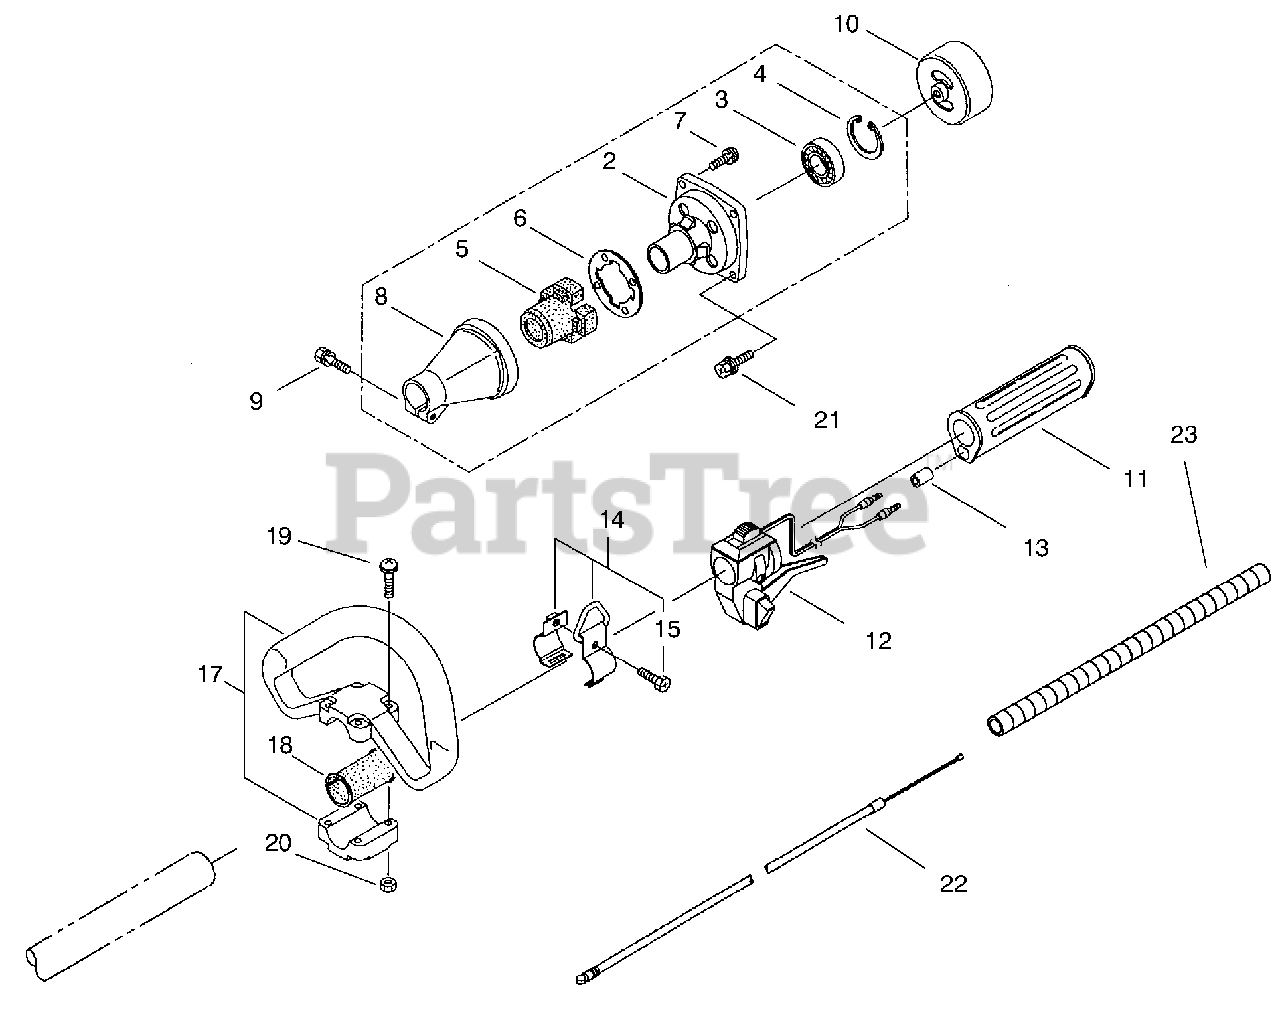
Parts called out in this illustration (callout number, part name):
2	Bearing Case
4	Snap Ring
8	Driveshaft Tube Adapter
10	Clutch Drum
11	Shaft Grip
12	Throttle Trigger
13	Outer Guide
14	Hanging Bracket Assembly (Incl. Ref. #15)
17	Loop Handle
22	Throttle Cable
23	Plastic Tube
